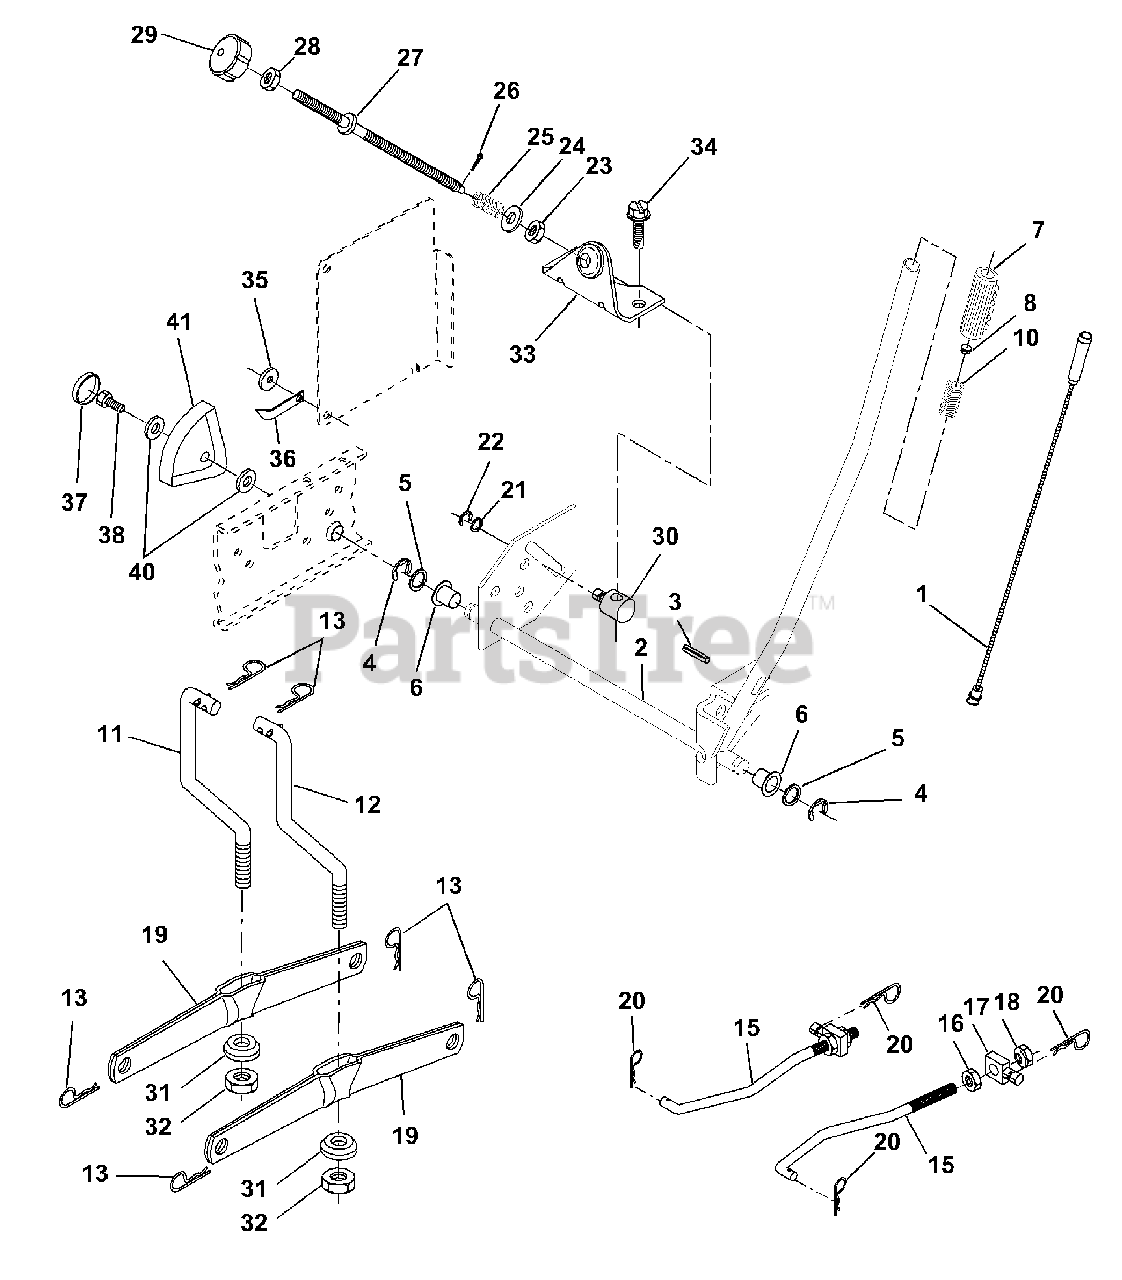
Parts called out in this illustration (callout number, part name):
1	Wire Asm Inner W/plunger 17.32
2	Shaft Asm Lift RH w/Inf
3	Pin Groove 1 500 Zinc
4	E Ring #5133-62
5	Washer 21/32 X 1 X 21 Ga
6	Bearing Nylon Blk 629 Id
7	Grip Handle Fluted Blk
8	Button Plunger Black
10	Spring Cprsn 3 750 Oiled
11	Link Lift LH Fixed Length
12	Link Lift RH Fixed Length
13	Retainer Spring
15	Link Front
16	Nut Jam Hex 1/2-13 Unc
17	Trunnion Blk Zinc
18	Nut Lock W/wsh 1/2-13unc
19	Arm Suspension Rear
20	Retainer Spring
21	Washer 15/32 X 3/4 X 16 Ga
22	Ring Klip #t5304-37
23	Nut Special
24	Washer 13/32 X 5/8 X 16 Ga
25	Spring 2-1/8"
26	Pin Cotter 3/32 X 1/2
27	Rod Adj Lift Zinc 7.49 Wrk Lg
28	Nut Hex Jam 3/8-16 Unc
29	Knob Inf 3/8-16 Unc Blk W/sym
30	Trunnion Dp Stop Dbl Thds PLT
31	Bearing Pvt Lift Spherical
32	Nut Nylock 3/8 - 24
33	Bracket, Stop Inf. Hgt.
34	Screw THDROL 3/8-16 x 1/2 TY-TT
35	Washer Nylon .44 x .75 x .032
36	Pointer Pnt Height ind .505
37	Plug Hole Blk 1.485/1.515 Dia.
38	Screw Thdrol 5/16-18 x 3/4
40	Washer 11/32 x 1-1/2 10 Ga.
41	Scale Ind. Height Blk.
